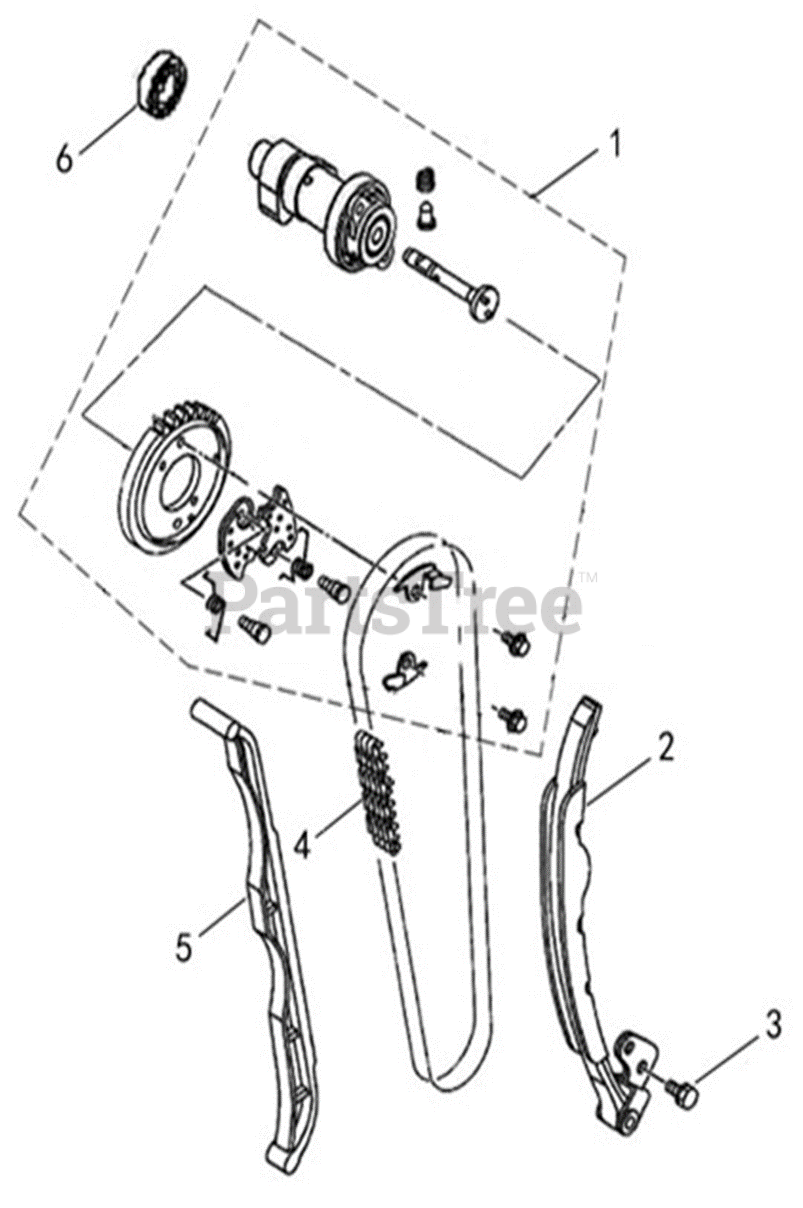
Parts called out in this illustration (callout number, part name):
1	CAMSHAFT ASSEMBLY
2	TENSIONER PLATE
3	HEX HEAD BOLT & PLAIN WASHER
4	TIMING CHAIN M7-6.35-124
5	CHAIN GUIDE
6	BEARING 6004Z
